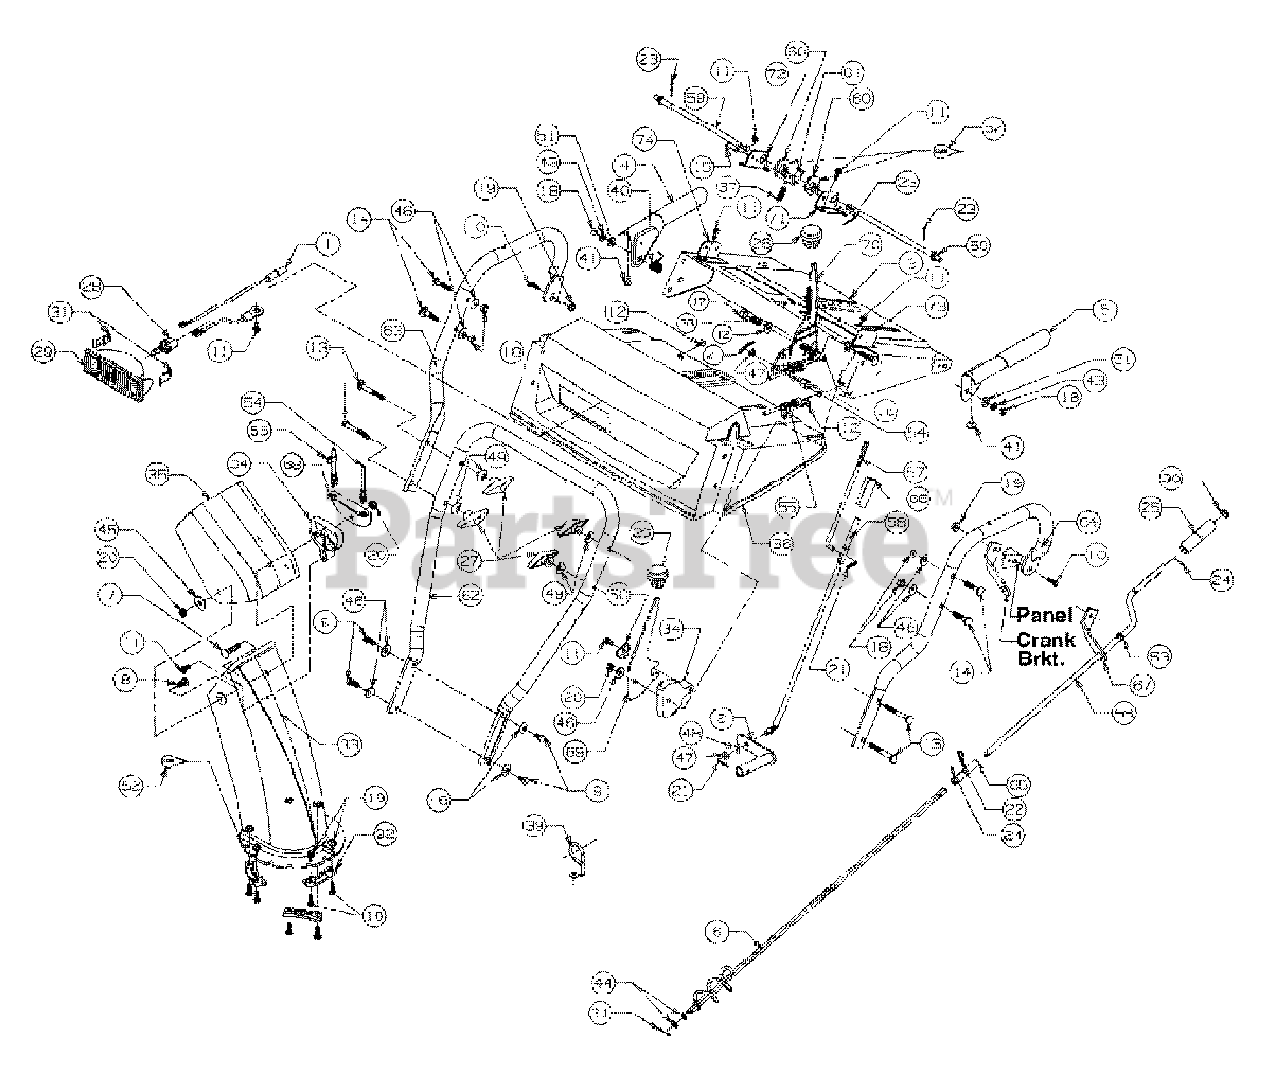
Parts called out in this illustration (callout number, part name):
1	Harness-Light
2	Arm-Shift
5	Handle-Engagement-L.H.
6	Crank-Chute
7	Bolt-Carriage
8	Bolt-Carriage
9	Screw-Hex
10	Screw-Hex
11	Screw-Washer Head-Hex
12	Screw-Hex
13	Bolt-Carriage
14	Bolt-Carriage
15	Pin-Clevis
16	Ferrule
17	Nut-Hex Lock
18	Nut-Hex
19	Nut-Hex Lock
20	Nut-Hex Lock
21	Pin-Cotter Internal
22	Pin-Cotter
24	Pin-Roll
25	Knob-Chute Crank
26	Knob-Shift
27	Knob-Wing Nut
29	Housing-Lamp
30	Cap-Push
31	Clip-Retaining
32	Keeper-Chute
33	Chute-Lower
34	Guide-Cable
35	Chute-Upper
36	Panel-Handle
37	Spring
38	Spring
39	Wire-Control
40	Spring
41	Bumper
42	Washer-Bell
43	Washer-Lock
44	Washer-Flat
45	Washer
46	Washer-Bell
47	Washer-Flat
48	Washer-Lock
49	Washer-Saddle
50	Washer
51	Washer
52	Lubricant
53	Bushing-Plastic
54	Cable-Chute Control
55	Cable-Chute Control
56	Crank-Chute
57	Rod-Shift Upper
58	Rod-Shift Lower
59	Rod-Cam
60	Cam-Handle Lock
61	Pawl-Handle Lock
62	Handle-Lower
63	Handle-R.H.
64	Handle-L.H.
65	Spacer
66	Connector
69	Handle-Chute Tilt
70	Handle-Shift
71	Bracket-Handle Support-L.H.
72	Bracket-Handle Support-R.H.
74	Bracket-Handle Support-R.H.
